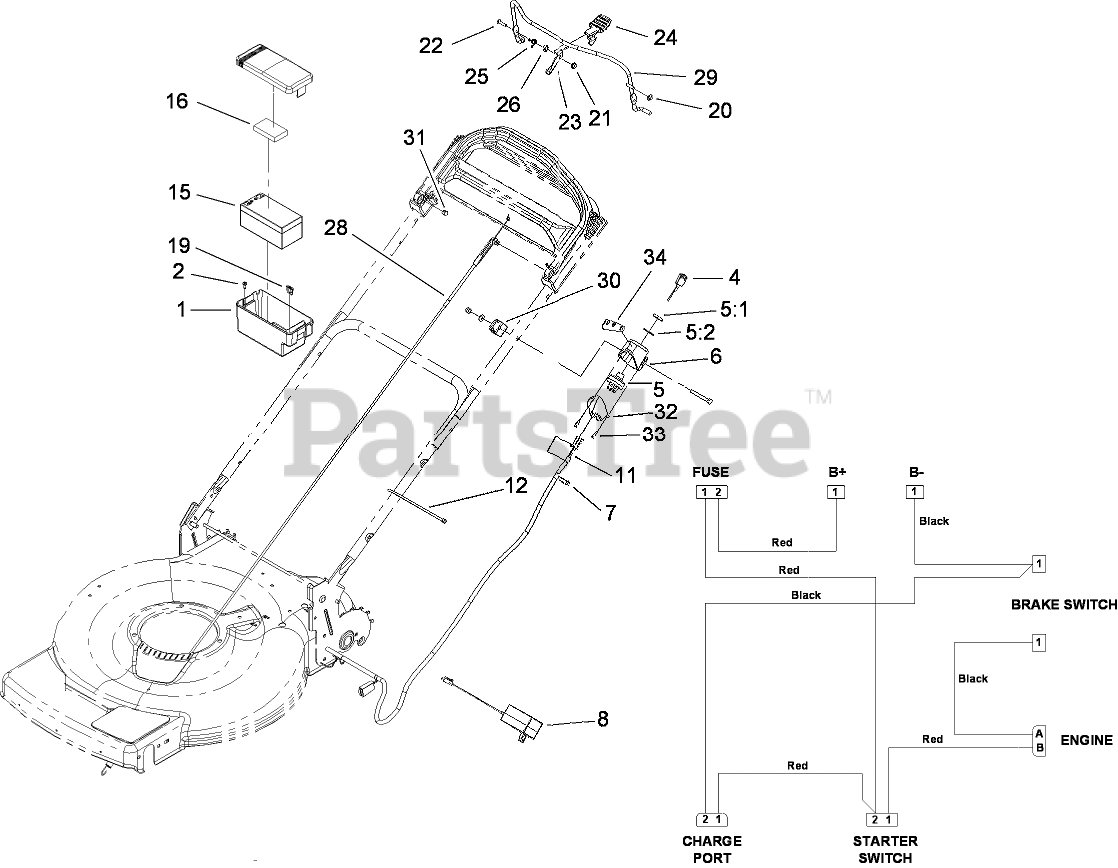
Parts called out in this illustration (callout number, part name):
1	BATTERY BOX ASM
2	SCREW-FORMING, THREAD
5	SWITCH-STARTER
5:1	NUT-HH
5:2	WASHER-TOOTH, INTERNAL
6	HOUSING-SWITCH, KEY
7	HARNESS-WIRE,
8	CHARGER-12 VOLT
11	DECAL-WARNING
12	TIE-CABLE
15	BATTERY-WET
16	FOAM-BATTERY, TOP
19	FUSE-40 AMP
20	NUT-SPEED
21	NUT-LOCK, FLANGE
22	SCREW-HWH
23	LEVER
25	SPRING-TORSION
26	SPACER
28	CABLE ASM
29	BAIL-BRAKE
30	ANCHOR-CABLE, UPPER
31	Plug-Dome
32	COVER-SWTCH
33	SCREW-PPH
34	DECAL-SWITCH, IGNITION
